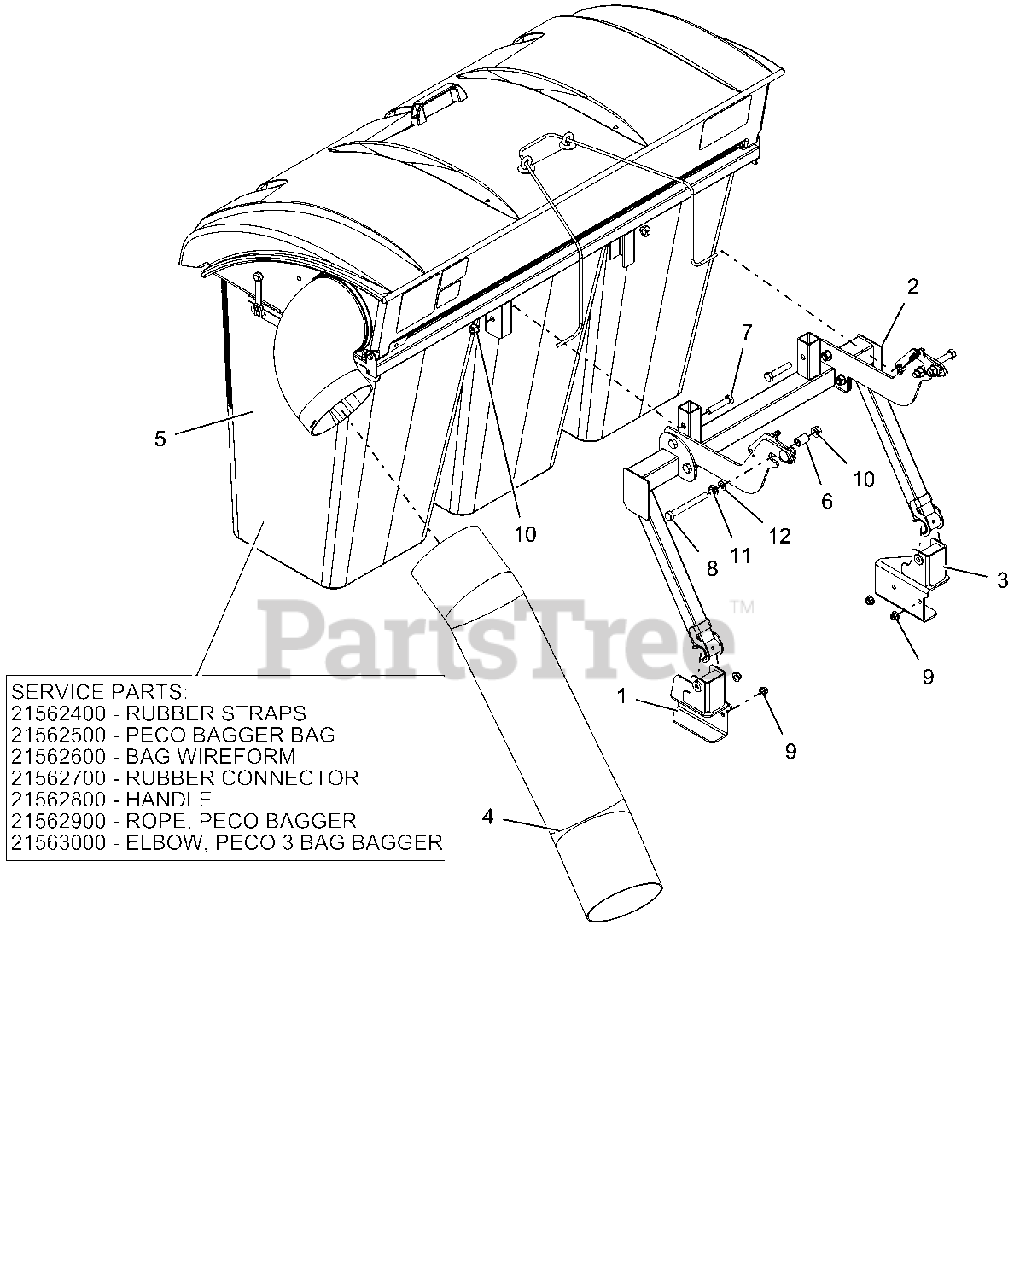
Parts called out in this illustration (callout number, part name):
1	WLDMT, BAGGER MOUNT RH (BLACK)
2	WLDMT, BAGGER POST (BLACK)
3	WLDMT, BAGGER MOUNT LH (BLACK)
4	HOSE, BAGGER 7 X 49
5	BAGGER, PECO 3 BAG RECEPTACLE
5	RUBBER STRAPS
5	PECO BAGGER BAG
5	BAG WIREFORM
5	RUBBER CONNECTOR
5	HANDLE
5	ROPE, PECO BAGGER
5	ELBOW, PECO 3 BAGGER
6	SPACER, .510 X .750 X 1.148
7	BLT-HEX .50-13X2.50 GR5 YWZC
8	BLT-HEX .50-13X4.50 GR8 FULL THD YWZC
9	NUT-LK-NYL-FLG .38-16 YWZC
10	NUT, LK-TOP-FLG .50-13 YWZC
11	NUT .50-13 WIZ FLANGE
12	WSHR-FL-STL .505X.880X.072 YWZC
